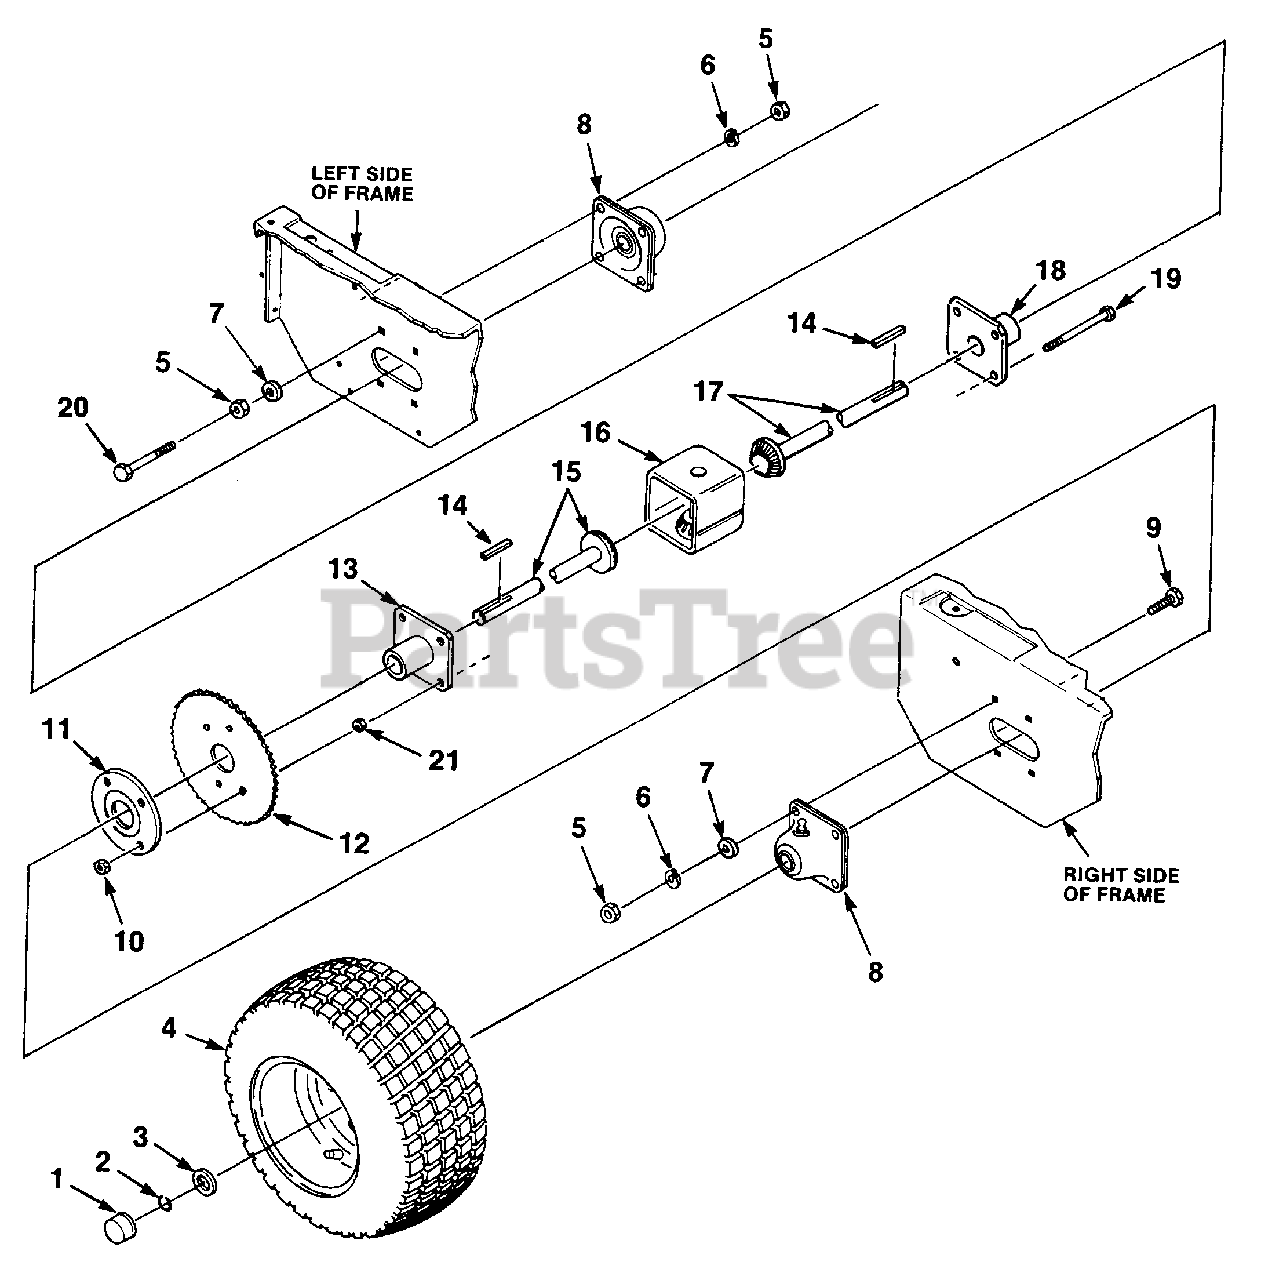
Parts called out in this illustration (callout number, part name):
2	RING- Retaining
4	WHEEL & TIRE
5	NUT- Hex 3/8-16
6	WASHER- Lock 3/8
7	WASHER- Plain 3/8
9	SCREW- Hex centerlock 3/8-16 x 2 1/4
10	NUT- Hex centerlock 3/8-16
13	CAP & BEARING (R.H.)
15	AXLE- R.H. w/gear
16	HOUSING & GEAR
17	AXLE- L.H. w/gear
18	CAP & BEARING (L.H.)
19	SCREW- Hex 5/16-18 x 4
20	SCREW- 3/8-16 x 2 1/4
21	NUT- Hex jam
